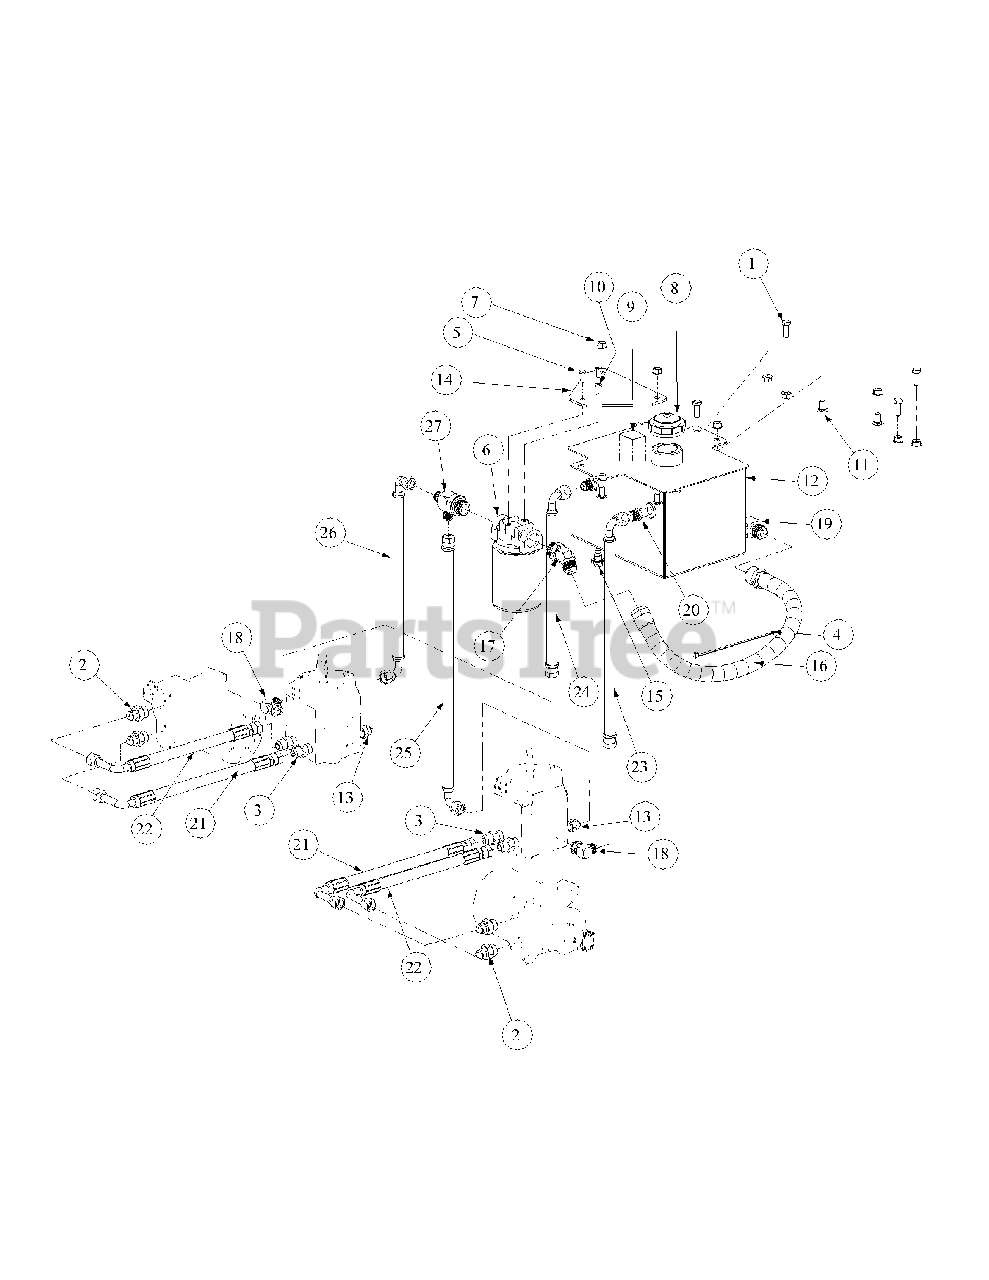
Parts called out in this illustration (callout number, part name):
1	Hex Cap Screw, 3/8-16, 1
2	Fitting 1/2 x 3/4 - O Ring
3	Fitting 1/2 x 1/2 - O Ring to Flare
4	Cable Tie, 3/16 x .05 x 7.4
5	Hex Cap Screw, 1/4-20, .75
6	Filter Head 3/4
7	Hex Nut Flange Lock, 3/8-16
8	Cap, Hydro Oil Tank
9	Decal Oil Only 20W50
10	Lock Washer, 1/4
11	Carriage Bolt, 3/8-16 x .75 LG.
12	Hydraulic Tank Assembly
13	Fitting Connector, 1/2 x 3/8
14	Oil Filter Mounting Plate
15	Oil Pan Drain Plug w/ Seal
16	Tank to Filter Hose Assembly
17	Fitting, 3/4 x3/4 x 45 degree
18	Elbow Fitting, 3/8 O-ring, 1/2 Flare
19	Fitting Elbow, 3/4 NPT x 1-1/16 Flare
20	Fitting, 3/8 NPT, 1/2 Flare
21	Long Pressure Hose Assembly
22	Short Pressure Hose Assembly
23	17.75" Return Hose Assembly, RH
24	14.25" Return Hose Assembly, LH
25	21.25" Supply Hose Assembly, RH
26	15.50" Supply Hose Assembly, LH
27	Tee Fitting, 3/4 x 1/2 x 1/2
